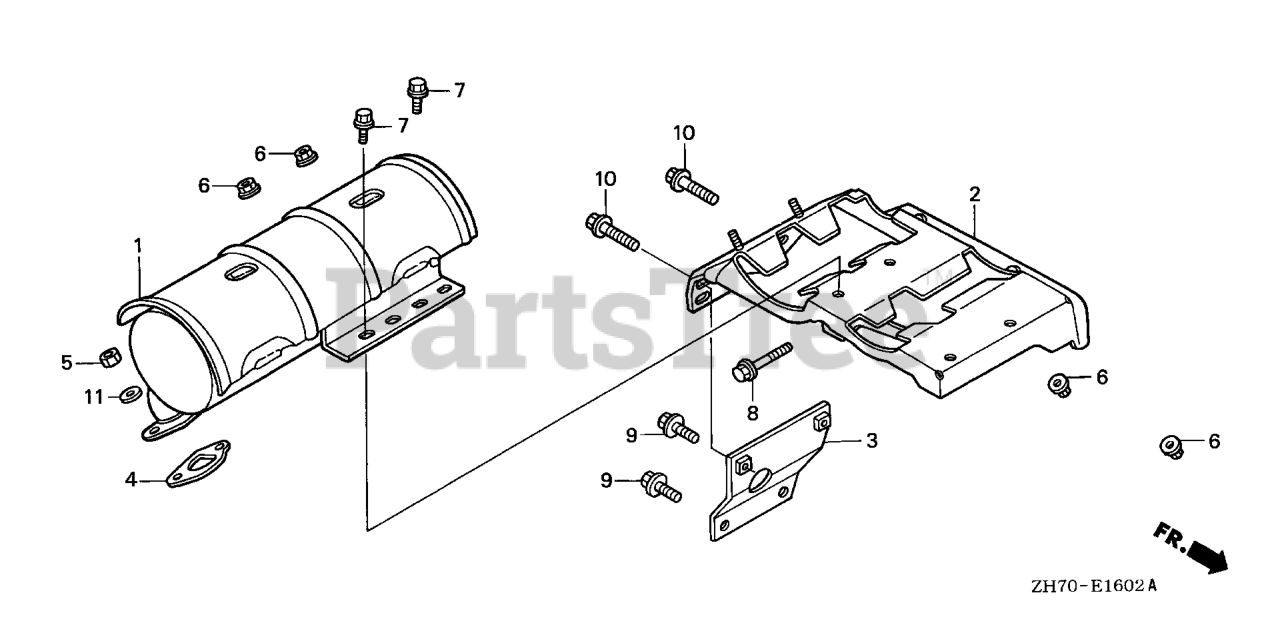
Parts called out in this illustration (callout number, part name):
2	STAY, MUFFLER
4	GASKET, MUFFLER
5	NUT, HEX. (8MM)
6	NUT, FLANGE (6MM)
7	BOLT, FLANGE (6X16) Use from Engine SN 2056820.
8	BOLT, FLANGE (6X25)
10	BOLT, FLANGE (8X20) Use up to Engine SN 1609606.
